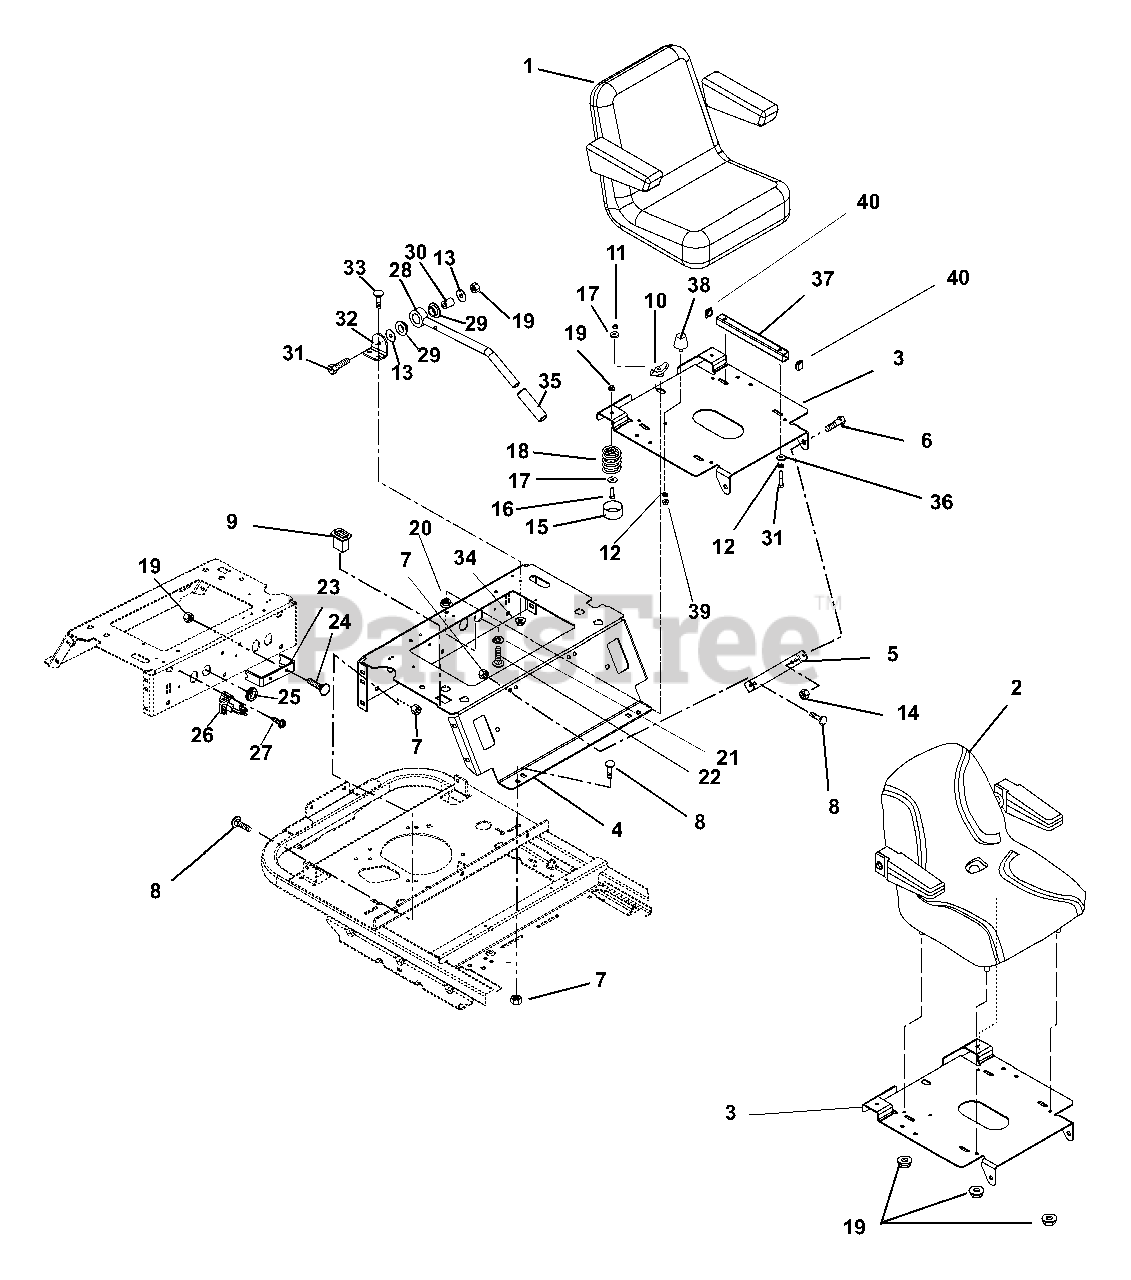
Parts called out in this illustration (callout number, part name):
1	SEAT,V-2505 MICHIGAN W/ARM
2	ASSM, SEAT W/REPLA ARMRESTS
2	KIT, COMPLETE ARMREST
3	BRACKET, SEAT PLATE
4	SEAT SUPPORT
5	BRACKET, SEAT PLATE
6	BOLT-SHLDR .375-16X.150
7	@NUT-LK-NYL-FLG .38-16 YWZC
8	@BLT-RDHDSQNK .38-16X1.00 G5YZ
9	HOUR METER - DIGITAL
9	PLUG, HOUR METER
10	KNOB - WING .312-18 UNC
11	@NUT-LK-NYL .312-18 YWZC
12	@WSHR-LK .31X.078 REG YWZC
13	WSHR-FL-STL .347X1.254X.048YWZ
14	@NUT-LK-TOP-FLG .38-16 YWZC
15	HUB CAP
16	@BLT-HEX .31-18X1.00 GR5 YWZC
17	WSHR-FL-STL .328X1.0X.094 YWZC
18	SPRING, SEAT
19	@NUT-LK-NYL-FLG .31-18 YWZC
20	@NUT-SPNLK-FLG .312-18 YWZC
21	WSHR-FL-STL .505X1.00X.062YWZC
22	BLT-RDHDSQSHNK.31-18X2.75G2YWZ
23	BRAKE ROD SUPPORT
24	@BLT-RDHDSQNK .31-18X1.00 G5YZ
25	GROMMET 1.0ID X 1.38 OD
26	SOLENOID
27	@SCR-TAP .25-20X.37 HWH YWZ TR
28	WMT, PARK BRAKE
29	BSHG-FLG .762X1.48X.44 NYL
30	SPACER .328 X .76 X 1.01
31	@BLT-HEX .31-18X1.75 GR5 YWZC
32	BRKT, BRAKE HANDLE PIVOT
33	@BLT-RDHDSQNK .25-20X.75 G5YZ
34	@NUT-LK-TOP-FLG .25-20 YWZC
36	WSHR-FL-STL .328X.87X.179 YWZC
37	SPACER, SEAT (LOW BACK)
38	BUMPER, RUBBER CONE,STUD MOUNT
39	@NUT-SPNLK-FLG .312-24 YWZC
40	CAPLUG SQR 1-14-20
